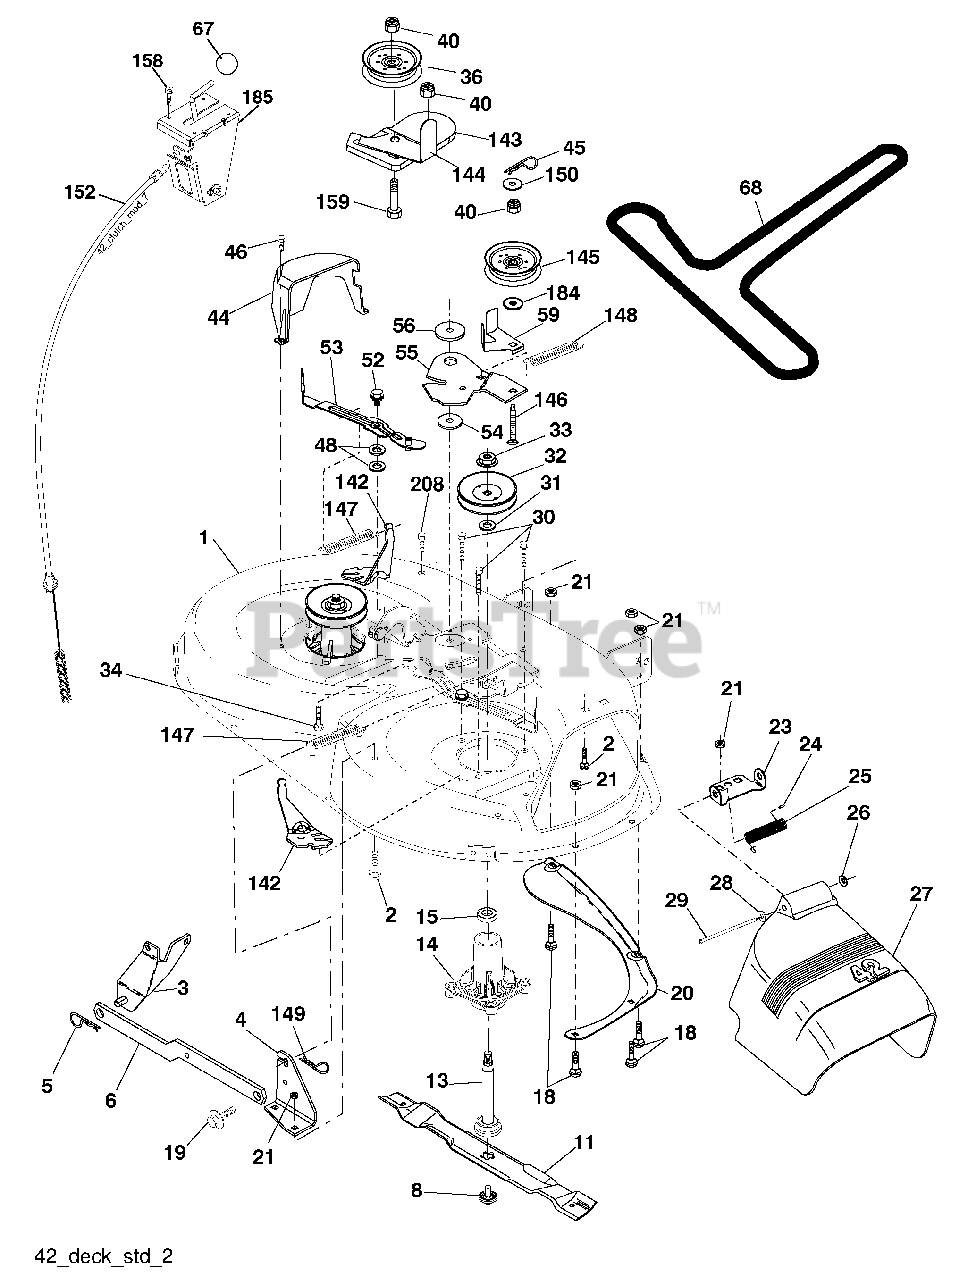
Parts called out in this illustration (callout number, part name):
1	Mower Deck Assembly, 42"
2	Bolt
3	Bracket Asm Fr. Sway Bar 3/42
4	Bracket Asm Deck 42" Sway Bar
5	Retainer Spring
6	Bar Sway Deck
8	Bolt/Washer Asm. 7/16-20 unf The following Blades are available)
11	Blade Mower 42" Hi-Lift (for bagging and discharging)
11	Blade, Mulching 42" Std (for mulching mowers only)
11	Blade Mulching 42" Premium (For better wear when mulching)
11	Blade 42 3N1
11	Blade 42 3N1 Premium
13	Shaft As m. Mandrel
14	Housing Mandrel
15	Bearing, Ball, Mandrel
18	Bolt, Carriage 5/16-18 x 5/8
19	Bolt, Shoulder
20	Baffle, Vortex
21	Nut
23	Bracket, Deflector Mower 42"
24	Cap, Sleeve 80 x 112 Blk Mower
25	Spring, Torsion, Deflector 2 52
26	Nut, Push Phos & Oil
27	Shield, Deflector 42" Blk
28	Washer 11/32 x 5/8 x 16 Ga.
29	Rod, Hinge 42" 6 75 w/G
30	Screw Thdrol
31	Washer, Spacer Mower Vented
32	Pulley, Mandrel
33	Nut, Toplock
34	Bolt Carr SH 3/8-16 x 1-1/2 Gr.5
36	Pulley, Idler, Flat
40	Nut Lock 3/8-16
44	Guard, Mandrel, LH
45	Retainer
46	Screw, Thdrol 1/4-20 x 5/8 T
48	Washer, Hardened
52	Bolt, Shoulder 5/16-18 unc
53	Arm Assembly, Pad, Brake
54	Washer, Hardened
55	Arm, Idler
56	Spacer, Retainer
59	Guard TUV Idler
67	Knob Round
68	V-Belt, 42" Mower
142	Anchor Spring Brake Mower
143	Bracket Arm Idler 42"
144	Keeper Belt 42" Clutch Cable
145	Pulley Idler Flat
146	Bolt Carriage Idler
147	Spring Extension
148	Spring Return Idler
149	Retainer Spring Yellow
150	Washer 9/32 x 3/4 x 10 Ga.
152	Clutch Cable 42"
158	Screw Hex Thd Cut 1/4-20 x 1/2
159	Bolt Rdhd Sqn 3/8-16 unc x 1-3/4
184	Washer 13/32 x 7/8 x 10 Ga.
185	Head Asm Cable Clutch
208	Screw 3/8-16 x 1/2
208	Mandrel Assembly
208	Replacement Mower, Complete
